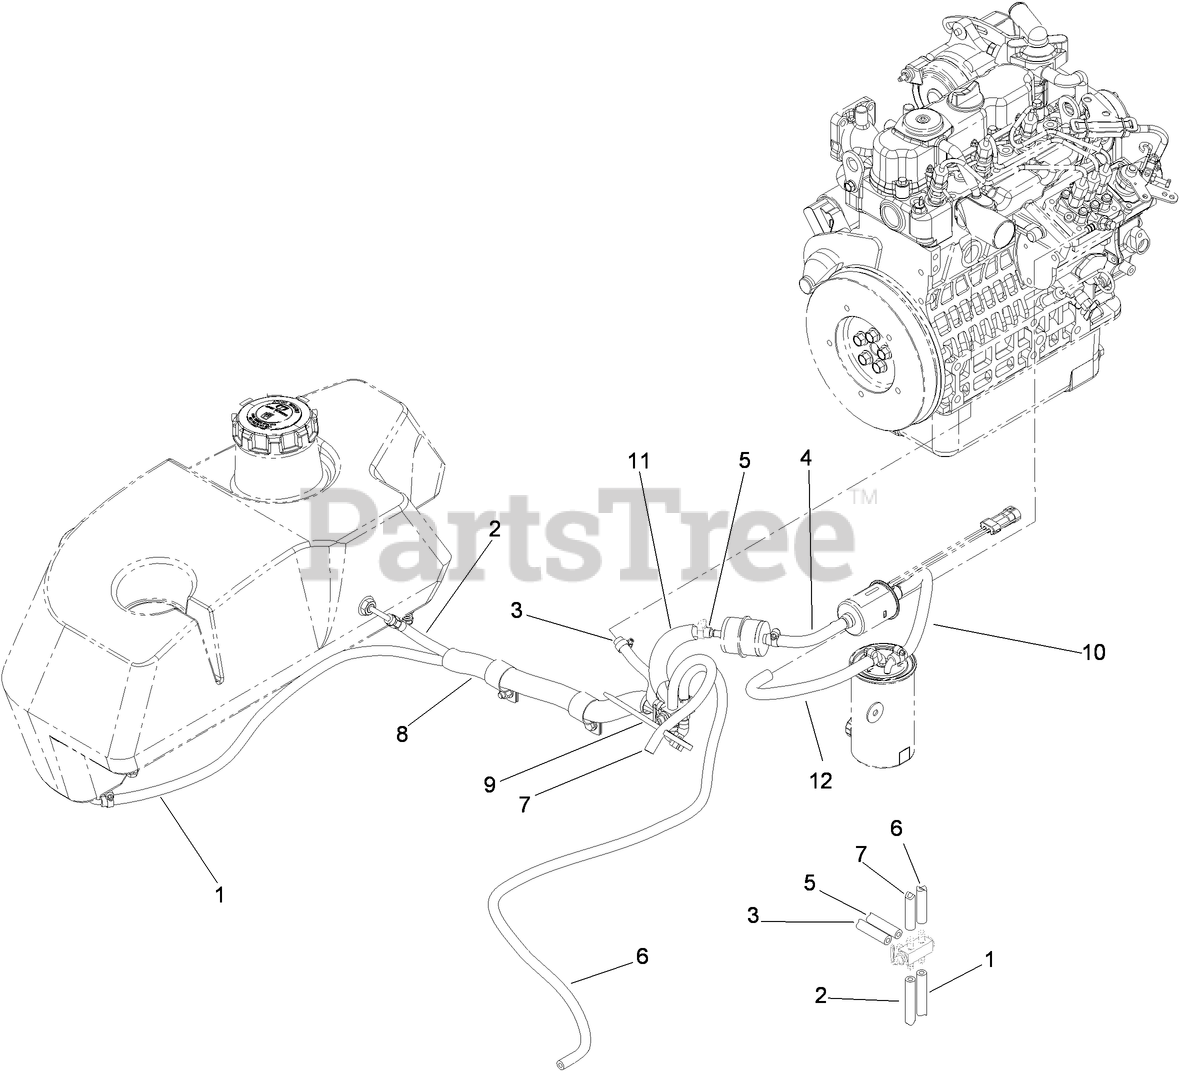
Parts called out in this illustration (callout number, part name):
1	HOSE-FUEL
2	HOSE-FUEL
3	HOSE-FUEL
4	HOSE-FUEL
5	HOSE-FUEL
6	HOSE-FUEL
7	HOSE-FUEL
8	SLEEVE-FABRIC
9	TIE-PLASTIC
10	HOSE-FUEL
11	CONDUIT-FUEL LINE
12	HOSE-FUEL
